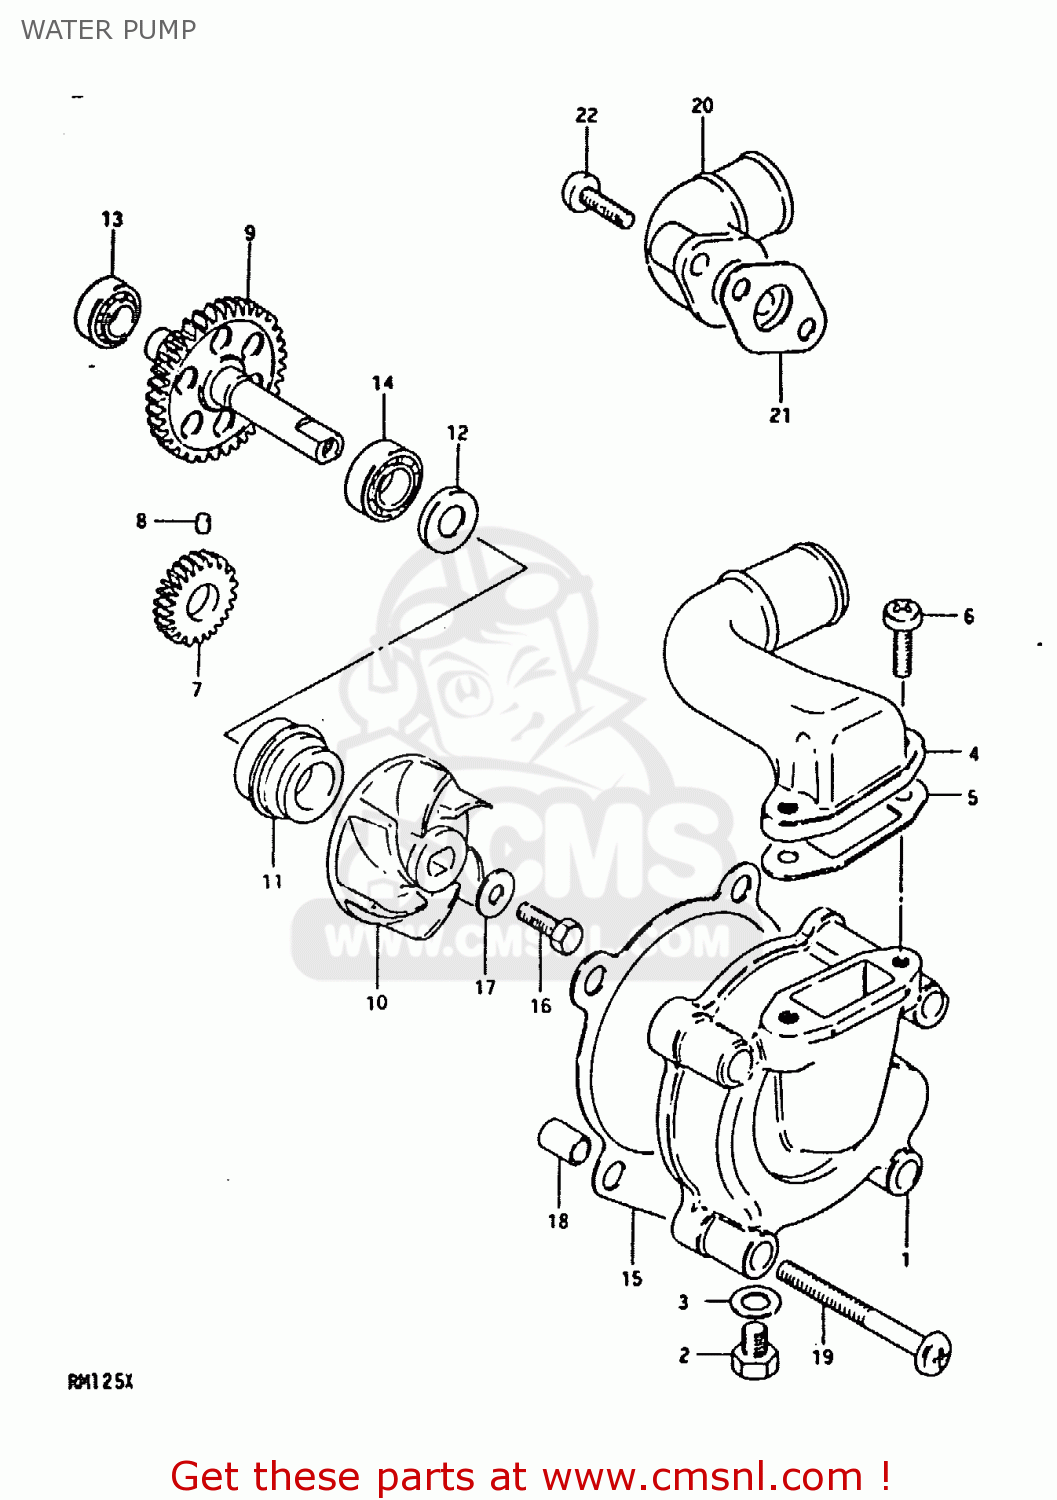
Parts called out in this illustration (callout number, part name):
1	CASE,WATER PUMP
2	BOLT 8X12
3	GASKET,DRAIN (NAS)
4	CONNECTOR
5	GASKET,WATER PUMP INLET (MCA)
6	SCREW
7	GEAR,WATER PUMP DRIVE
8	PIN 3X5
9	SHAFT,WATER PUMP
10	IMPELLER,WATER PUMP
11	SEAL,WATER PUMP SHAFT
12	SEAL,OIL(10X21X5)
13	BEARING(10X22X6)
14	BEARING
15	GASKET,WATER PUMP CASE (MCA)
16	BOLT
17	GASKET (NAS)
18	PIN
19	SCREW (6X45)
20	O-RING,WATER PUMP CASE
21	GASKET,WATER PUMP OUTLET (MCA)
22	SCREW
